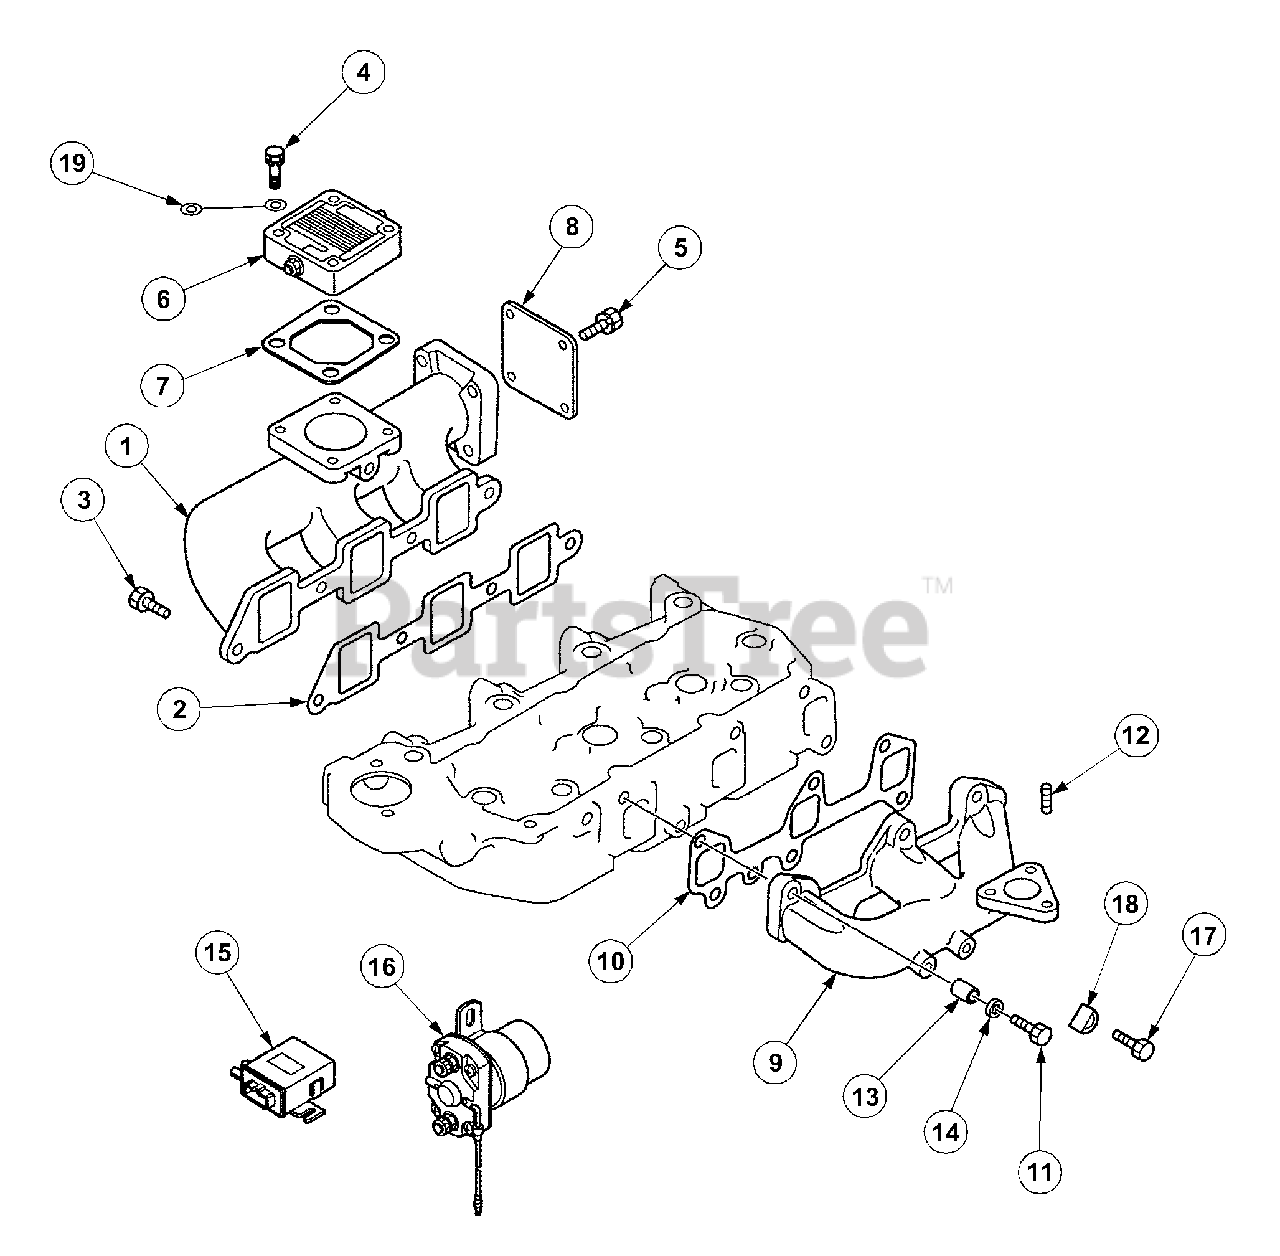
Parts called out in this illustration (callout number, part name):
1	Mainfold,Intake
2	Gasket,Intake
3	Bolt
4	Bolt,w/Washer
5	Bolt,w/Washer
7	Gasket,Air Heat
9	Mainfold,Exhaus
10	Gasket,Exhaust
13	Spacer
15	Controller,Heat
